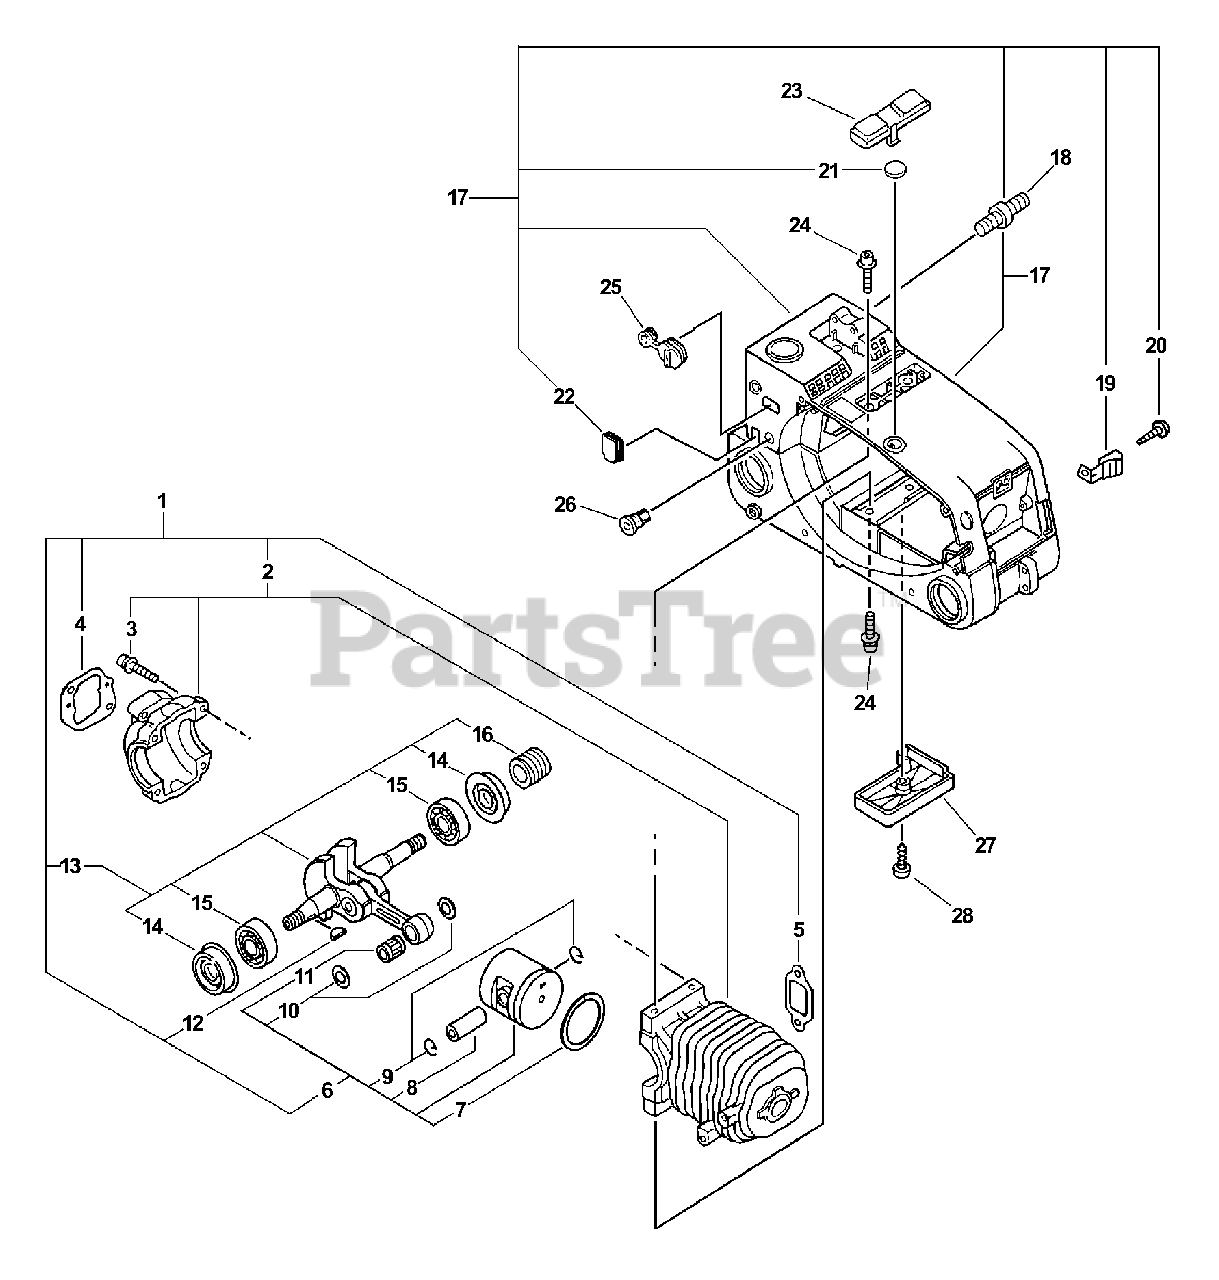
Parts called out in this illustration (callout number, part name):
1	SHORT BLOCK -- SB1018
2	CRANKCASE SET
3	SCREW - 5X25
4	GASKET, INTAKE
5	GASKET, EXHAUST
6	PISTON KIT
7	RING, PISTON
8	PIN, PISTON
9	RING, RETAINING
10	SPACER, PISTON
11	BEARING, NEEDLE
13	CRANKSHAFT ASSY
14	SEAL, OIL
15	BEARING, BALL - 6201
16	GEAR - WORM
17	ENGINE COVER KIT
17	COVER, ENGINE
18	STUD, GUIDE BAR
19	LATCH
20	SCREW - 4X10
21	PLUG
22	PLUG
23	COVER - GRAY
24	SCREW - 5X16
25	GROMMET
26	GROMMET
27	COVER, BOTTOM - GRAY
28	SCREW - 4X16
